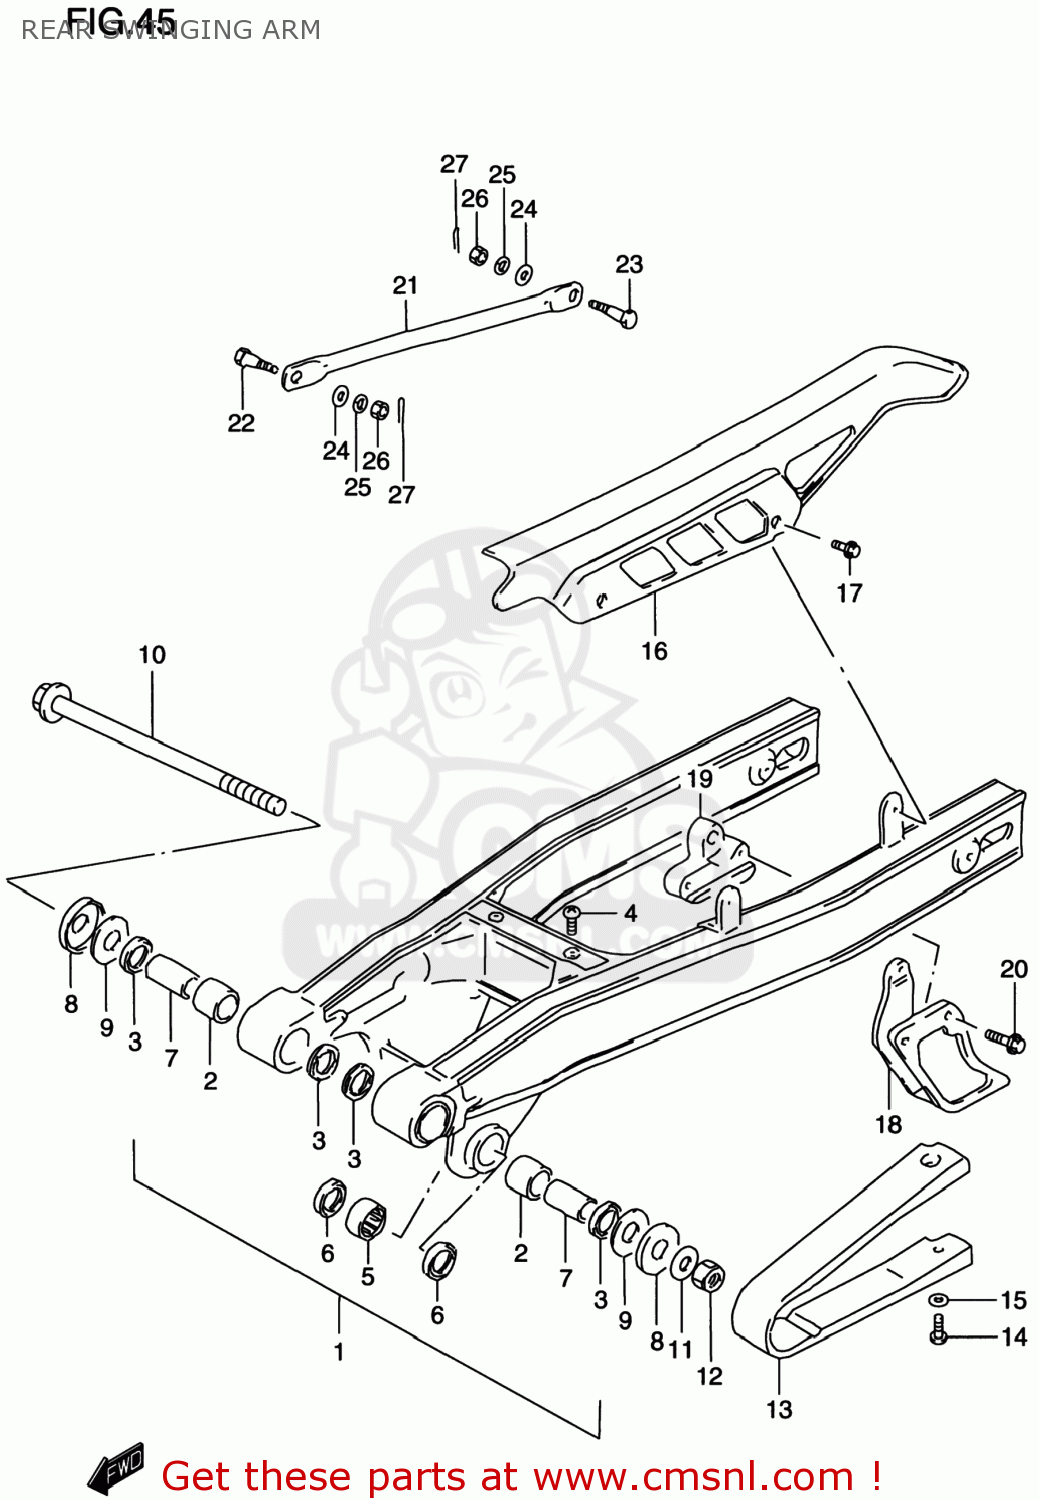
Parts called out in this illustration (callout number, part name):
1	SWINGINGARM ASSY,RR
2	BUSHING,RR SWGARM PIVOT
3	SEAL,OIL(20X27X5)
4	SCREW
5	BEARING(20X27X25)
6	SEAL,CUSHION LEVER OUT DUST
7	SPACER,RR SWGARM PVT
8	COVER,RR SWGARM DUST SEAL
9	WASHER
10	SHAFT,RR SWINGINGARM PIVOT
11	WASHER(14.2X24X2.3)
12	NUT
13	BUFFER,CHAIN TOUCH DEFENSE
14	SCREW
15	WASHER
16	CASE,CHAIN
17	BOLT(6X10)
18	GUIDE,CHAIN
19	RUBBER,CHAIN GUIDE
20	BOLT
21	TORQUELINK,RR
22	BOLT,TORQUE LINK,FRONT
23	BOLT(8X26.5)
24	WASHER
25	WASHER,LOCK
26	NUT
27	PIN 20X20
